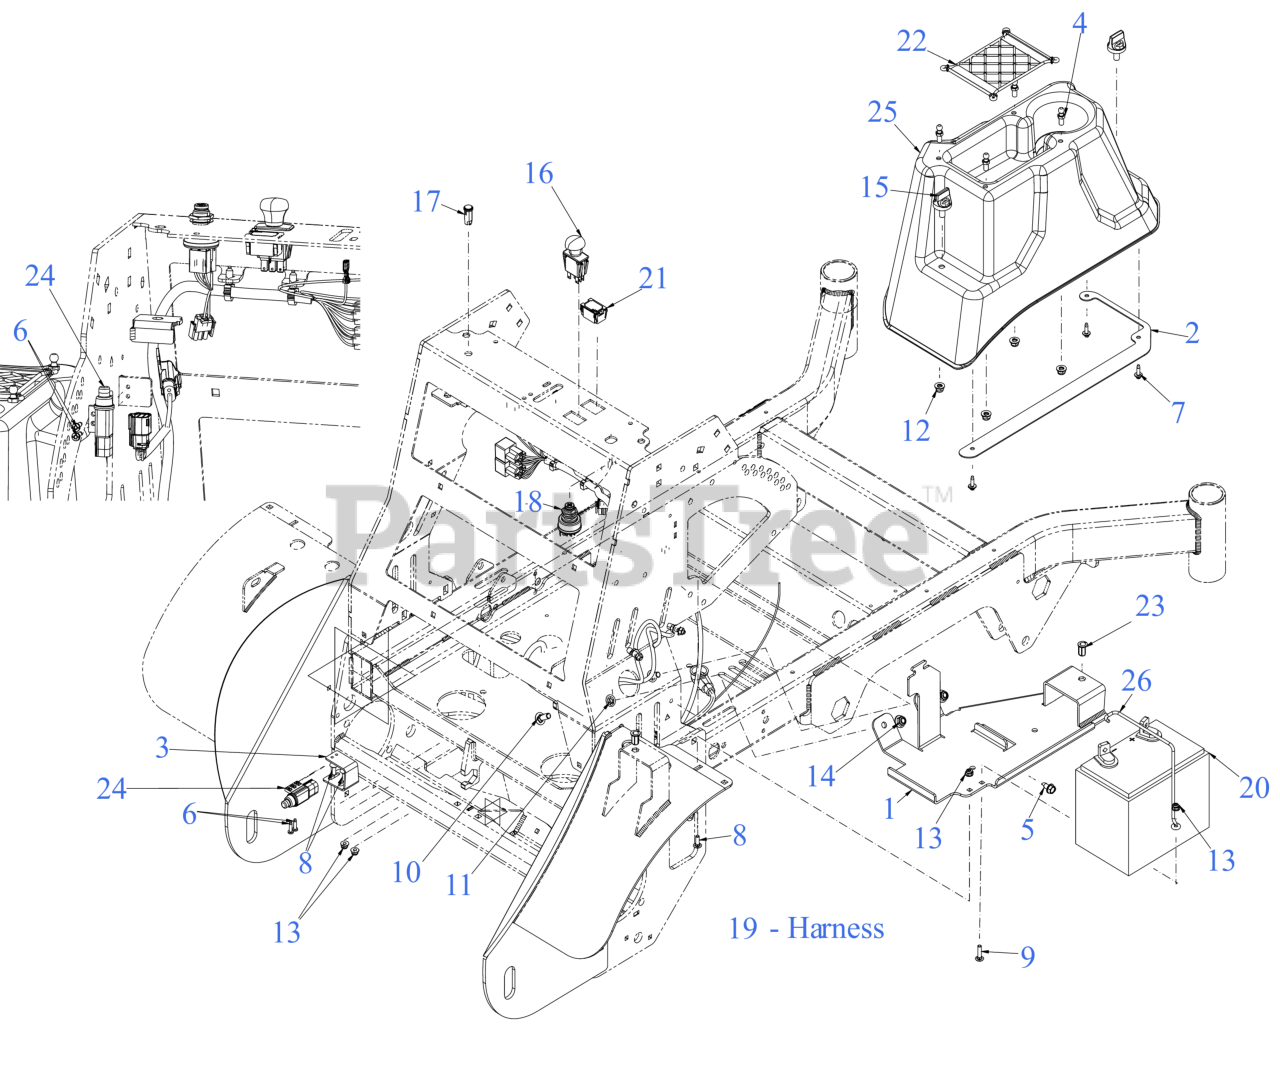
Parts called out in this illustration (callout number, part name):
1	BATTERY MOUNT BRACKET
2	BATTERY COVER SUPPORT PLATE
3	OPC MOUNT BRACKET
4	BALL STUD 5/16-18
5	SCREW 5/16-18 x .750
6	SCREW (10-24X.75:PH:TAP:T25:GR5)
7	SCREW 1/4-10 x .750
8	SCREW 1/4-20 x .75 GR5
9	SCREW 1/4-20 x 1 GR5
10	CARRIAGE BOLT 3/8-16 x 1.00 GR5
12	FLANGE LOCK NUT 5/16-18
13	FLANGE LOCK NUT
15	KNOB 3/8-16 x .875
16	PTO SWITCH (BLACK KNOB) TEXT SYM
17	INDICATOR LIGHT-RED
18	KEY SWITCH
19	HARNESS (EFI KAW)
20	BATTERY (230 CCA AGM U1-280)
21	HOUR METER
23	RIV NUT 3/8-16
24	SEALED PLUNGER SWITCH
25	BATTERY COVER
26	BATTERY SUPPORT ROD
